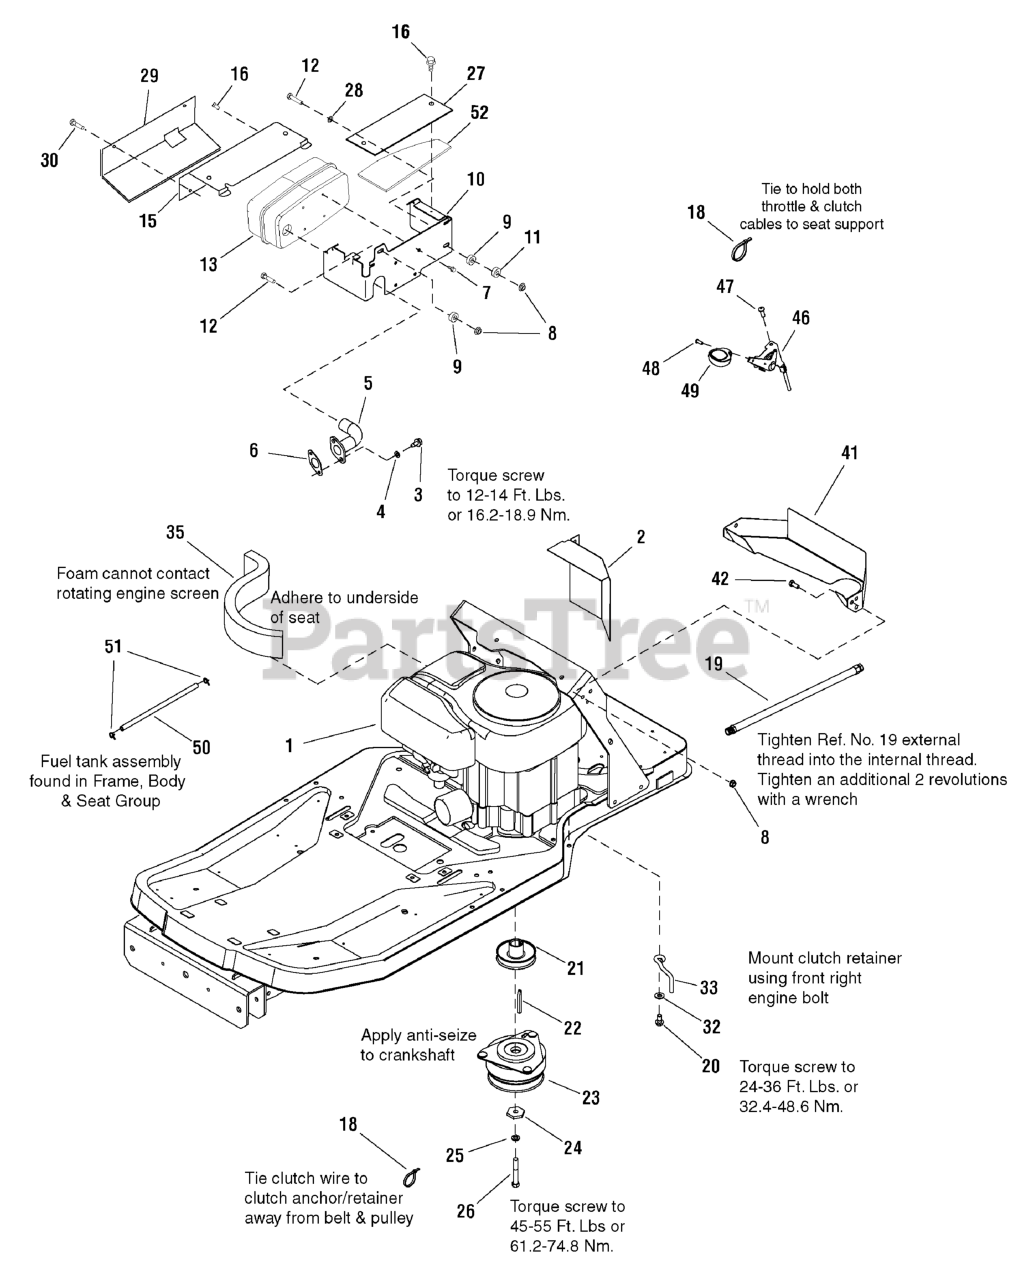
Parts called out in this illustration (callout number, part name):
1	ENGINE, 21HP B&S Intek, 49 State
2	HEAT SHIELD, Inner
3	CAPSCREW, Hex Head, 5/16-18 x 3/4, G8
4	LOCKWASHER, Spring, 5/16
5	PIPE ASSEMBLY, Exhaust
6	GASKET, Exhaust
7	SCREW, Hex Whiz Lock Flange, 1/4-20 x 5/8
8	NUT, Hex Whiz Lock Flange, 5/16-18
10	BRACKET, Muffler/Heat Shield
11	SPACER, .390 ID x .9 OD x .34 LG, Powdered Metal
12	CAPSCREW, Hex Head, 5/16-18 x 1-3/4, G5
13	MUFFLER ASSEMBLY, Single
15	HEAT SHIELD, Outer Single
16	CAPSCREW, Thread Cutting, # 10 x 1/2
18	TIE, Self Locking, 3-5/8 LG
19	HOSE, Oil Drain, 16-1/2 LG
20	SCREW, Hex Washer Head Taptite, 3/8-16 x 1-1/4
21	PULLEY ASSEMBLY, Engine
22	KEY, Hi-Pro, 1/4 x 2-1/2
23	CLUTCH, Electric
24	WASHER, Hex, .453 ID x 1-1/2
25	LOCKWSHER, Spring, .438
26	CAPSCREW, Hex Head, 7/16-20 x 2-3/4, G5
27	HEAT SHIELD
28	WASHER, 5/16
29	HEAT SHIELD
30	RIVET, Pop
32	WASHER, 3/8, .41 ID x .87 OD x .08 THK
33	RETAINER, Clutch
35	SEAL, Foam Air Duct, 1 x 2-1/2, 12" LG
41	AIR DUCT, Inlet
42	CAPSCREW, Hex Head, 5/16-18 x 3/4, G5
46	CONTROL, Throttle
47	SCREW, Pan Head Taptite Torx, 1/4-20 x 5/8
48	SCREW, Pan Head Taptite Combo, 310-16 x 3/4
49	KNOB, Throttle
50	HOSE, Fuel, 19.5"
51	CLAMP, Hose
52	INSULATION, Foam
